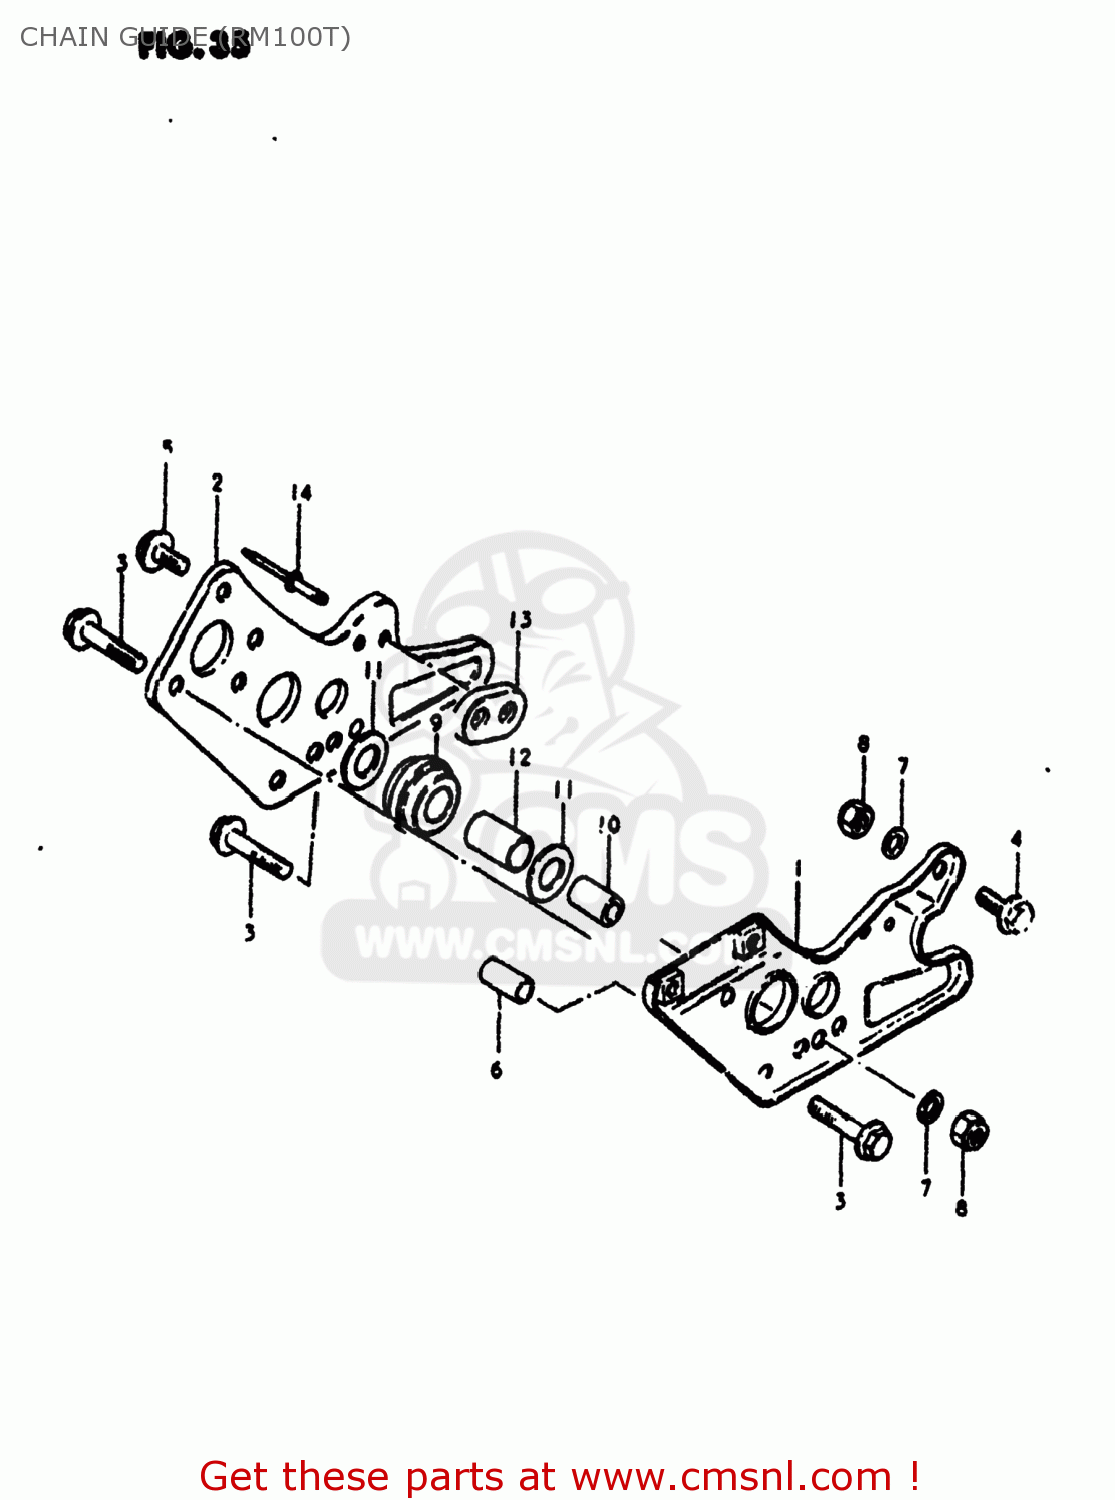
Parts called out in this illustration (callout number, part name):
1	PLATE,CHAIN GUIDE,OUTER
2	PLATE,CHAIN GUIDE,INNER
3	BOLT 6X35
4	BOLT
5	BOLT
6	SPACER(6.8X10X24.2)
7	WASHER
8	NUT 6MM
9	ROLLER,CHAIN GUIDE
10	SPACER,CHAIN GUIDE ROLLER
11	WASHER
12	BUSHING
13	PAD,DRIVE CHAIN GUIDE
14	RIVET
